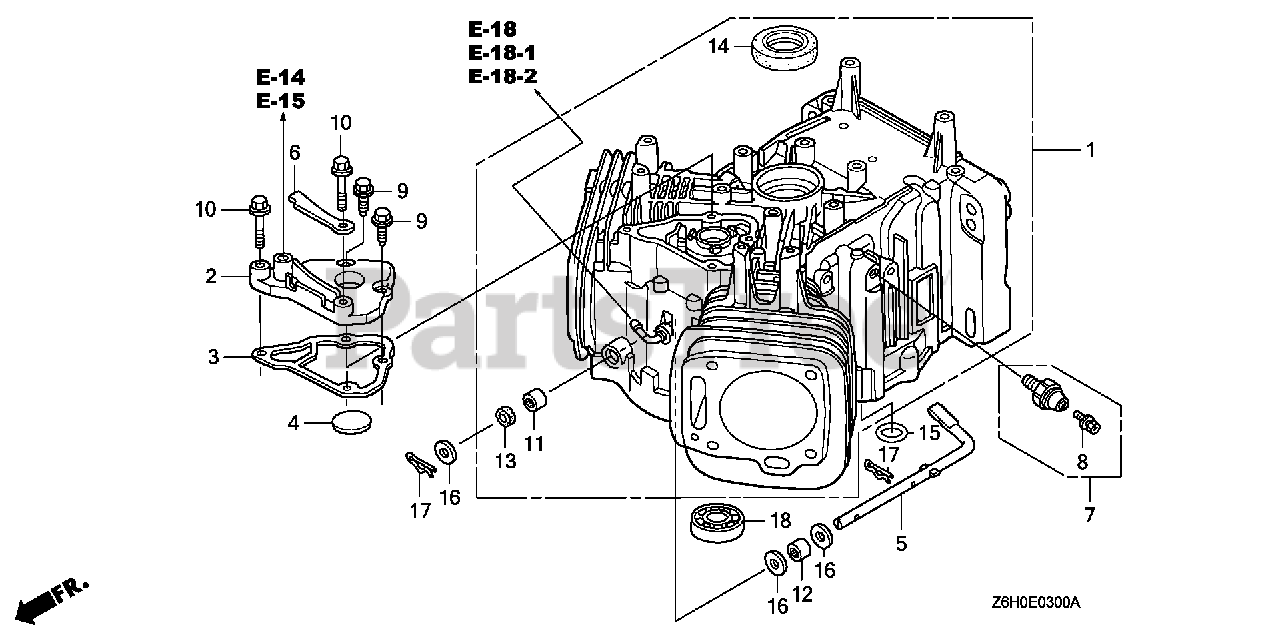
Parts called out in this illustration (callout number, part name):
1	CYLINDER ASSY.
2	COVER, BREATHER
3	GASKET, BREATHER COVER
4	VALVE, BREATHER
5	SHAFT, GOVERNOR ARM
6	CLAMP, WIRE
7	SWITCH ASSY., OIL PRESSURE
8	SCREW-WASHER (4X8)
9	BOLT, FLANGE (6X16) (CT200)
10	BOLT, FLANGE (6X32) (CT200)
11	BEARING, NEEDLE (8X12.7X11.1)
12	BEARING, NEEDLE (8X12X10)
13	OIL SEAL (8X14X5)
14	OIL SEAL (38X58X9)
15	O-RING (13X3.0)
16	WASHER, PLAIN (8MM)
17	PIN, LOCK (8MM)
18	BEARING, RADIAL BALL (6003)
